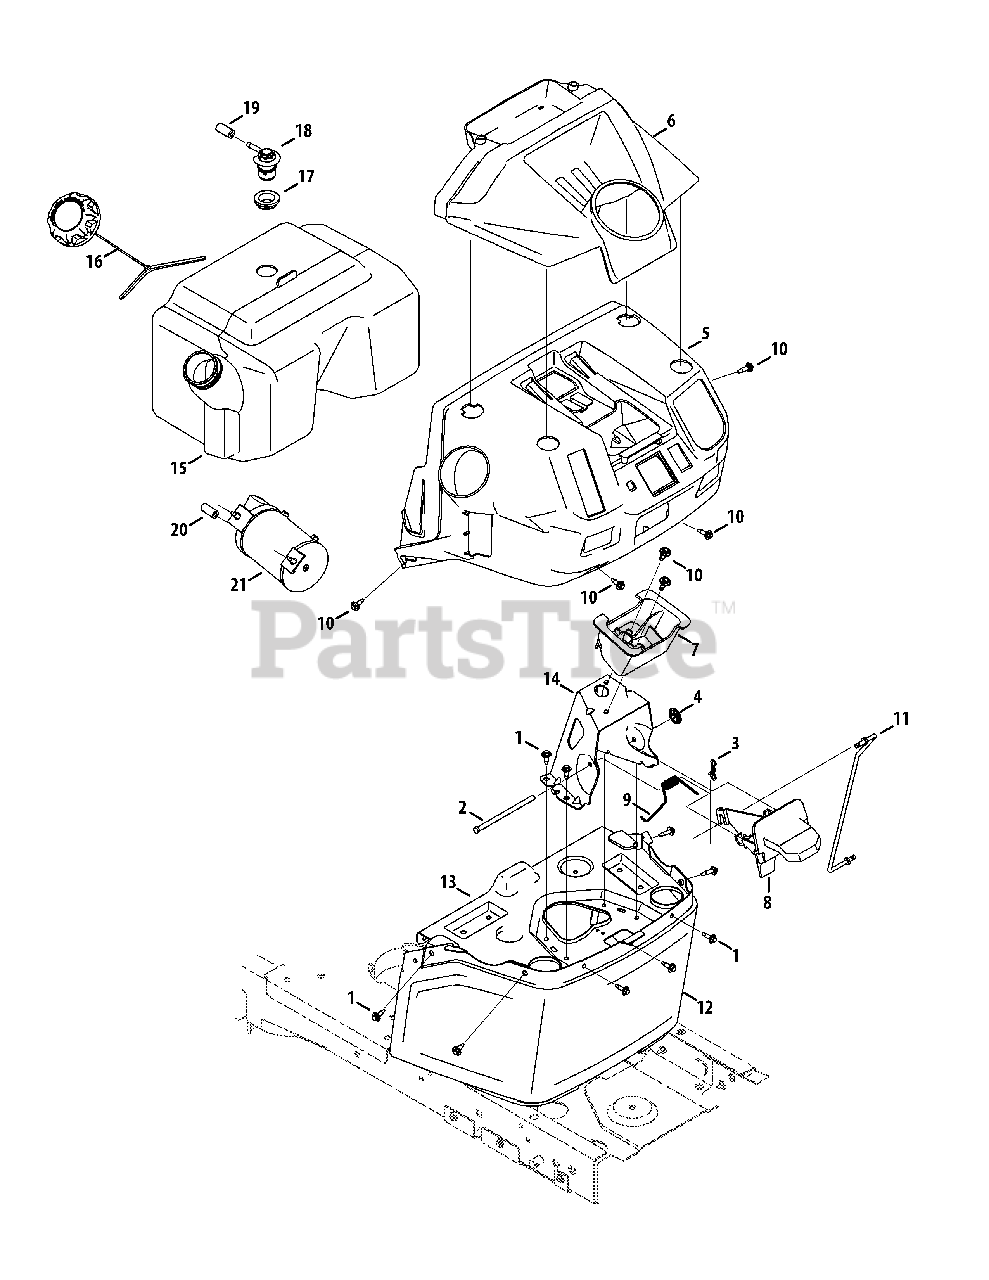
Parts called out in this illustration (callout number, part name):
1	Screw, M6-1 x .625
2	Hinge Pin, .25 Dia x 4.50 LG
3	Pin, Cotter, Bow-Tie 72
4	Push Nut, .25 dia.
5	Upper Dash
6	Dash Cap
7	Steering Shaft Bearing
8	Dash Lever
9	Torsion Spring, .330 ID
10	Shoulder Screw, .368 x .115, M6-1
11	Control Rod
12	Lower Dash
13	Dash Plate
14	Steering Bearing Mounting Bracket
15	Tank, Fuel, 3 Gal.
16	Cap, Fuel Carb
17	Grommet, Rubber, 23.0 ID
18	Valve, Rollover Grommet
19	Hose Vent (CARB)
20	Hose, Fuel, Low Perm, 7/32 Yellow (CARB)
21	Carbon Canister (CARB)
